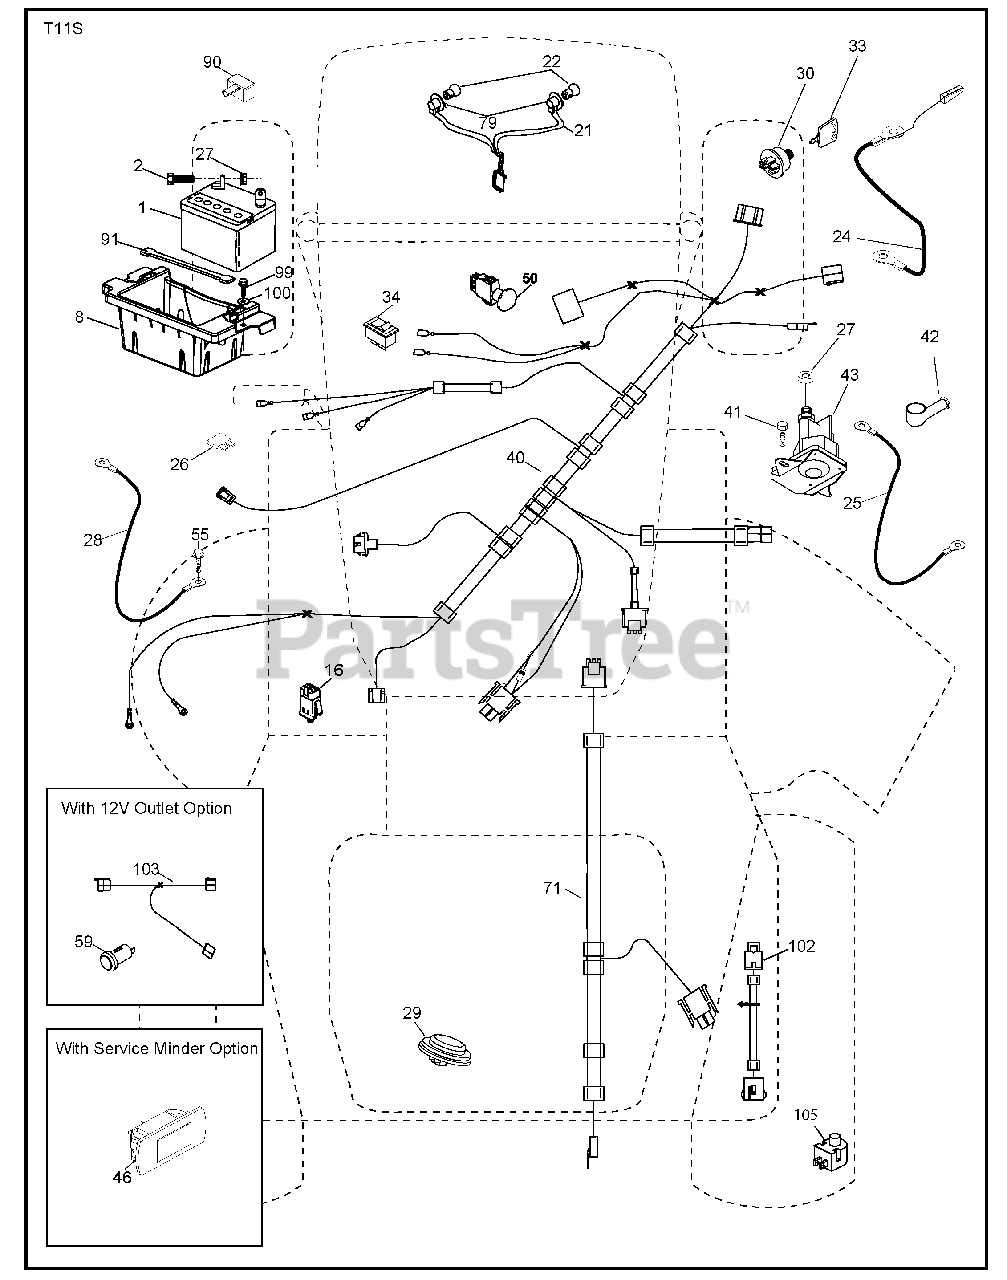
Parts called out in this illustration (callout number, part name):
1	Battery
2	Bolt Hex Hd 1/4-20 unc x 3/4
8	Battery Box
16	Switch Interlock
21	Harness Socket Light
22	Bulb, Light #1156
24	Cable Battery
25	Cable Starter
27	Nut Keps Hex 1/4-20 unc
28	Cable Ground 21" Blk 6 Ga.
29	Switch Seat
30	Switch Ign
33	Key/Chain
34	Switch Light/Reset
40	Harness Ign. Dash
41	Screw Thd Cut 1/4-20 x 1/2
42	Cover Terminal Red
43	Solenoid
46	Gauge Hourmeter
50	Switch PTO
55	Screw Thdrol 5/16-18 x 3/4
71	Harness Ign
79	Socket Asm. Bulb Twistlock
90	Cover Terminal Battery
91	Strap Battery
99	Screw Hexwsh Thdrol 1/4-20 x 3/4
100	Washer 9/32 x 7/8 x 16 Ga.
102	Harness Pigtail
105	Switch Reverse TT Pedal Control
